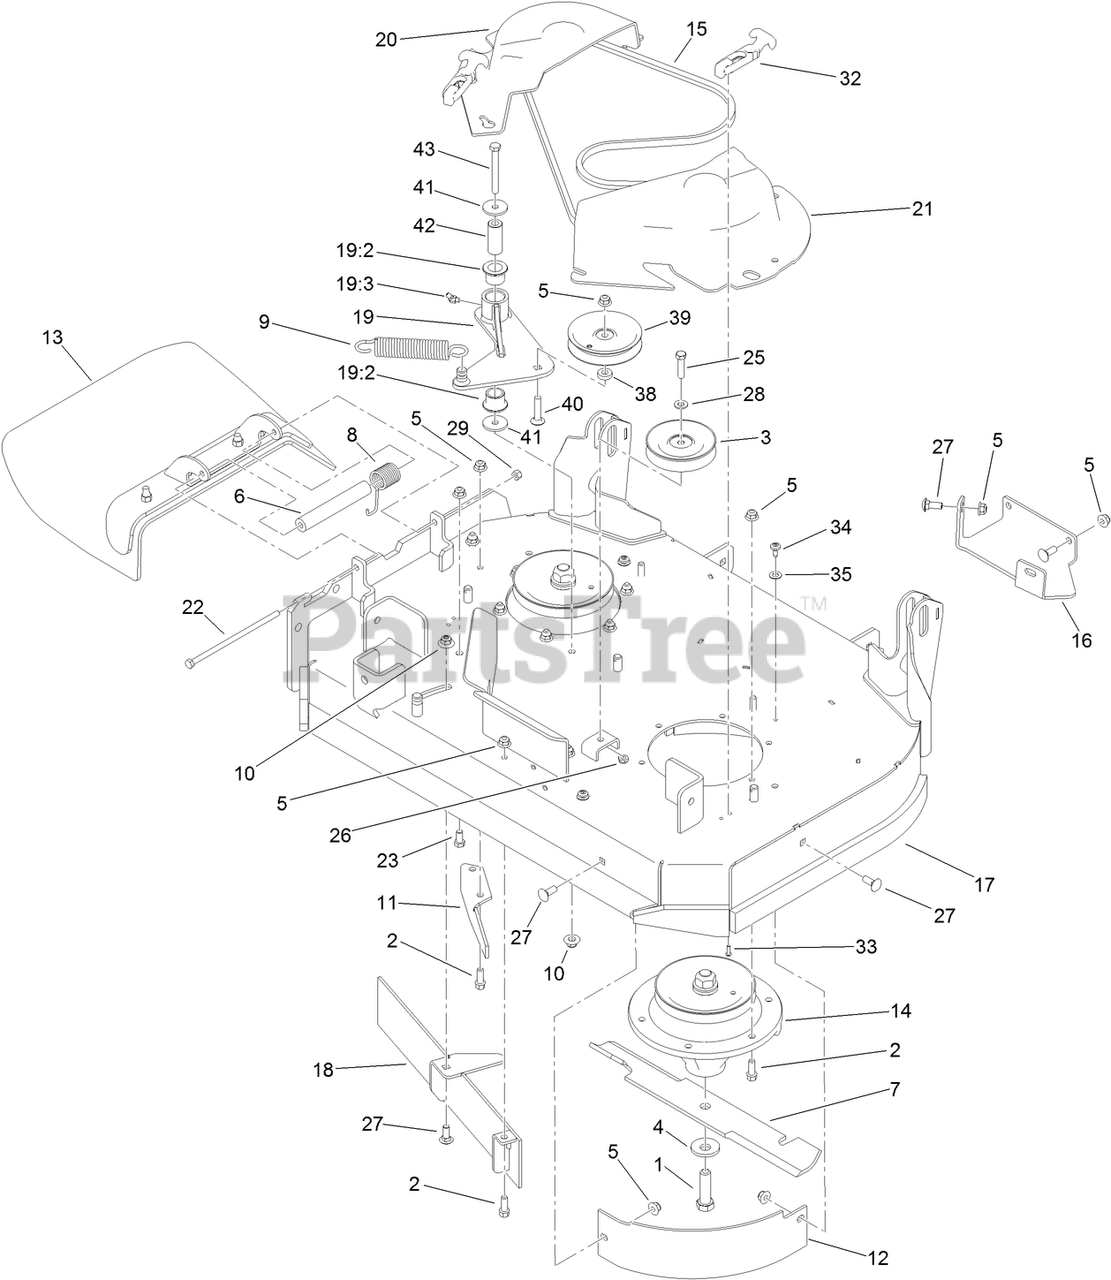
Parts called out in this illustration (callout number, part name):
1	SCREW-BLADE
2	SCREW-HWH
3	PULLEY-IDLER
4	Washer-Blade Bolt, Heavy
5	NUT-HF, NI
6	SPACER
7	BLADE-18IN, HI FLOW
8	SPRING-TORSION
9	SPRING-EXTENSION
10	NUT-FLANGE, NI
11	BAFFLE-DISCHARGE
12	BAFFLE-FRONT, LH
13	DEFLECTOR ASM
14	SPINDLE ASM
15	BELT-V
16	PLATE-SKID
17	DECK AND DECAL ASM
18	FRONT BAFFLE ASM
19	IDLER ARM ASM
19:2	BUSHING
19:3	FITTING-LUBE, 45 DEG
20	COVER-BELT, RH
21	COVER-BELT, LH
22	SCREW-HH
23	SCREW-HH
25	SCREW-HH
26	NUT-LOCK, NI
27	BOLT-CARR
28	WASHER-FLAT
29	NUT-LOCK, NI
32	LATCH-RUBBER
33	SCREW-HSBH
34	SCREW-SHOULDER
35	WASHER-THRUST
38	SPACER
39	PULLEY-IDLER
40	SCREW-CARR
41	WASHER
42	SPACER-PLAIN
43	SCREW-HH
